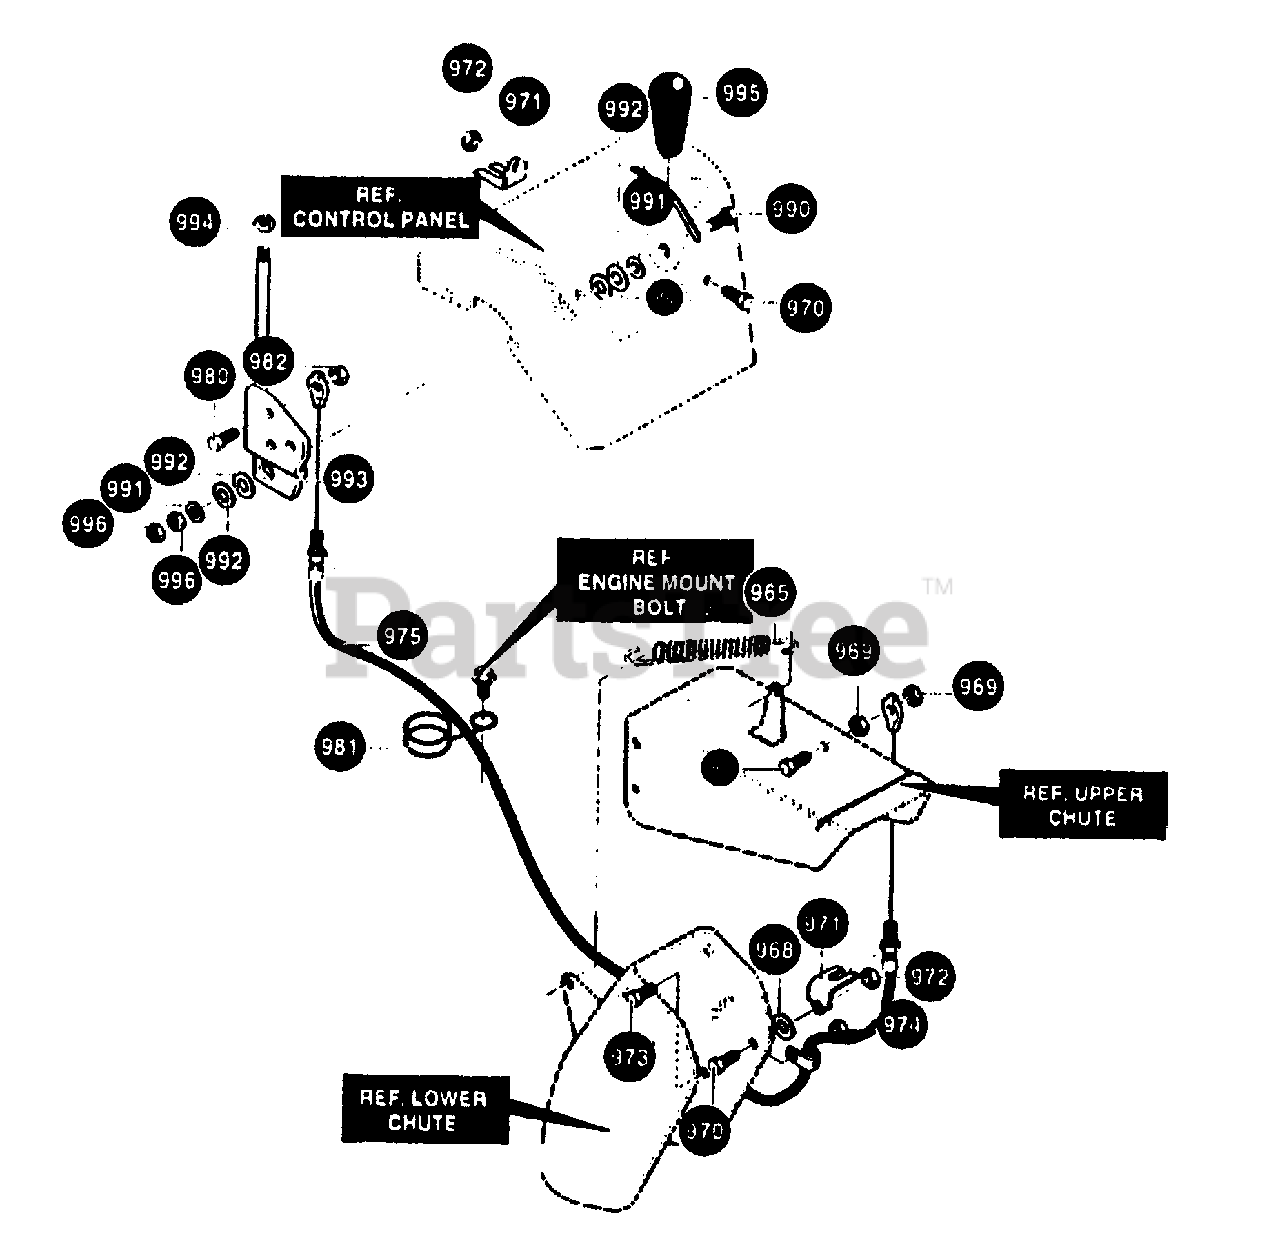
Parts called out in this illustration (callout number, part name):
965	SPRING, TENSION
967	SCREW, 1/4-20 X 1.00
968	WASHER, FLAT .344 X .69 X .065
969	NUT, 1/4-20
970	SCREW, 5/16-18 X .75
971	BRACKET, CABLE CHUTE
972	NUT, 5/16-18
973	SCREW, 10-24 X .38
974	NUT, #10-24
975	CABLE, CHUTE
980	SCREW, 1/4-20 X .75
982	NUT, 1/4-20
990	SCREW, 3/8-16 X .75
991	WASHER, FLAT .406 X .81 X .065
992	WASHER, SPRING
993	HANDLE, ASSY
994	NUT, 3/8-16
995	HANDLE, 3/8-16
996	NUT, 3/8-16
